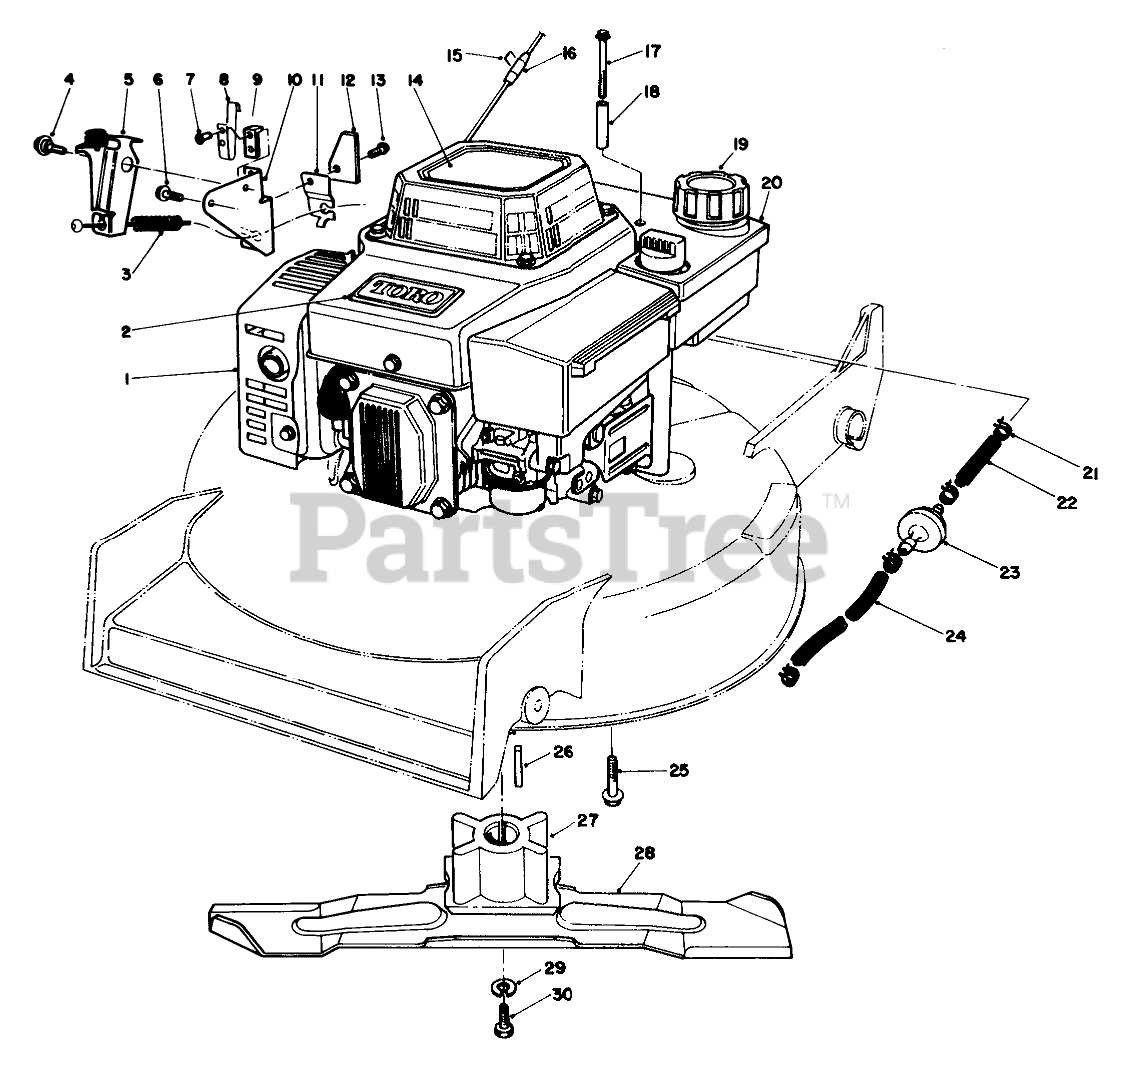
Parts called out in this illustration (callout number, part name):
1	Engine
2	TORO LOGO PLT
3	SPRING-COMPRESSION
4	Screw-Shoulder
5	BRAKE PLATE ASM
6	THO FORM SCREW M6 X 1
7	RIVET-PLASTIC
8	STRAP-GROUND
9	Strap-Insulation
10	Plate-Mounting
11	CABLE CLAMP
12	STOP-GROUND STRAP
13	SCREW
14	DECAL-HV INT'L
15	Staple
17	THRD FORMING SCREW
18	TUBULAR SPACER
19	GAS CAP ASM
20	TANK ASM
21	CLAMP-FUEL LINE
22	LINE-GAS
23	FILTER-FUEL
24	HOSE-FUEL
25	SCREW-HWHTF
26	KEY-SQUARE
27	Retainer Blade
28	BLADE-21in
29	WASHER-LOCK
30	SCREW-BLADE
